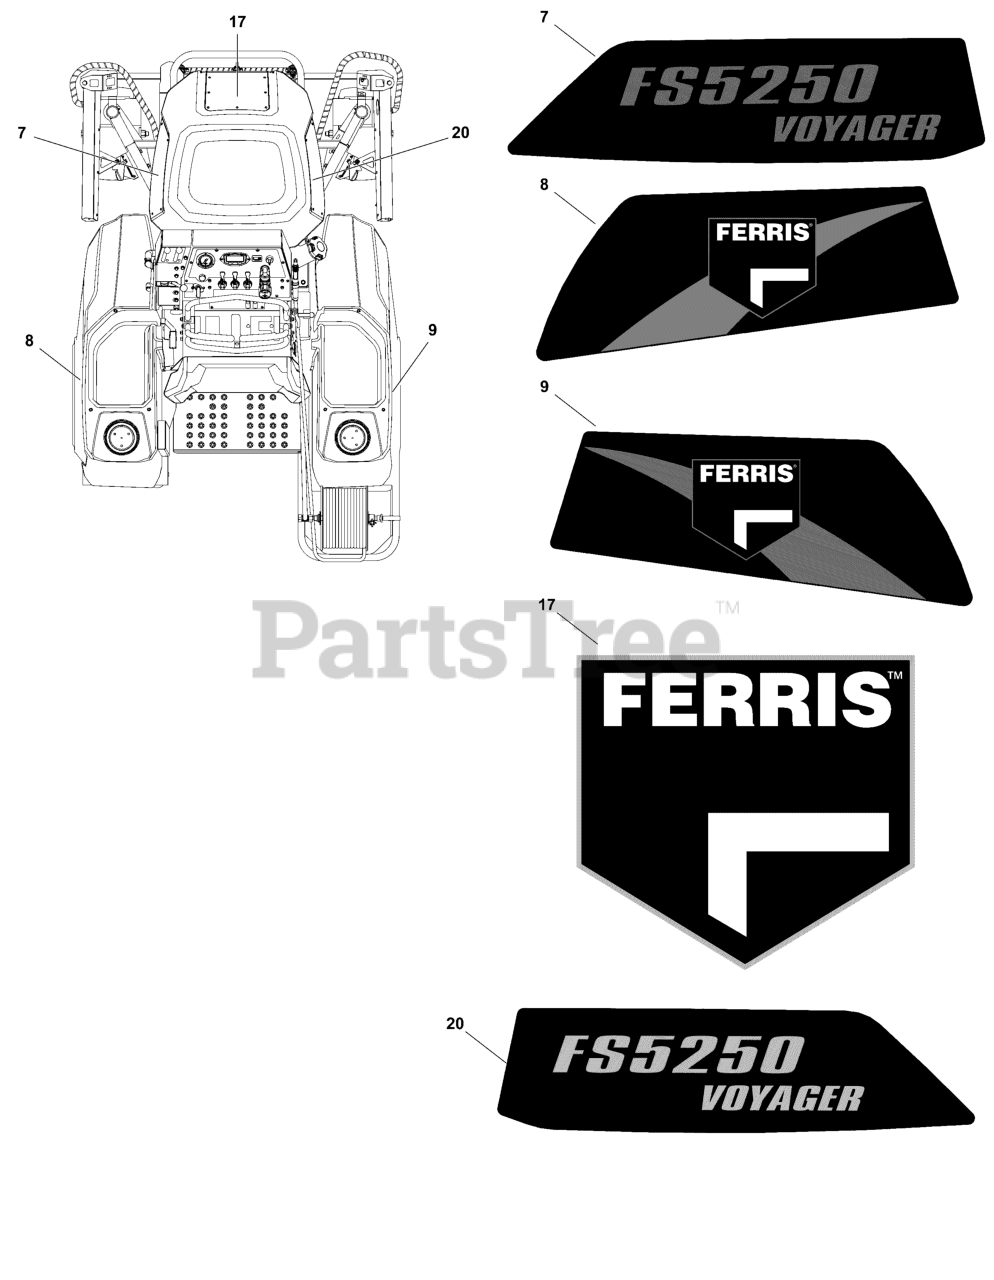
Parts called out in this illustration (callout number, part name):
7	DECAL, BRANDING HOPPER LH
8	DECAL, BRANDING TANK LH
9	DECAL, BRANDING TANK RH
17	DECAL, FERRIS SHIELD TM LARGE
20	DECAL, BRANDING HOPPER RH
